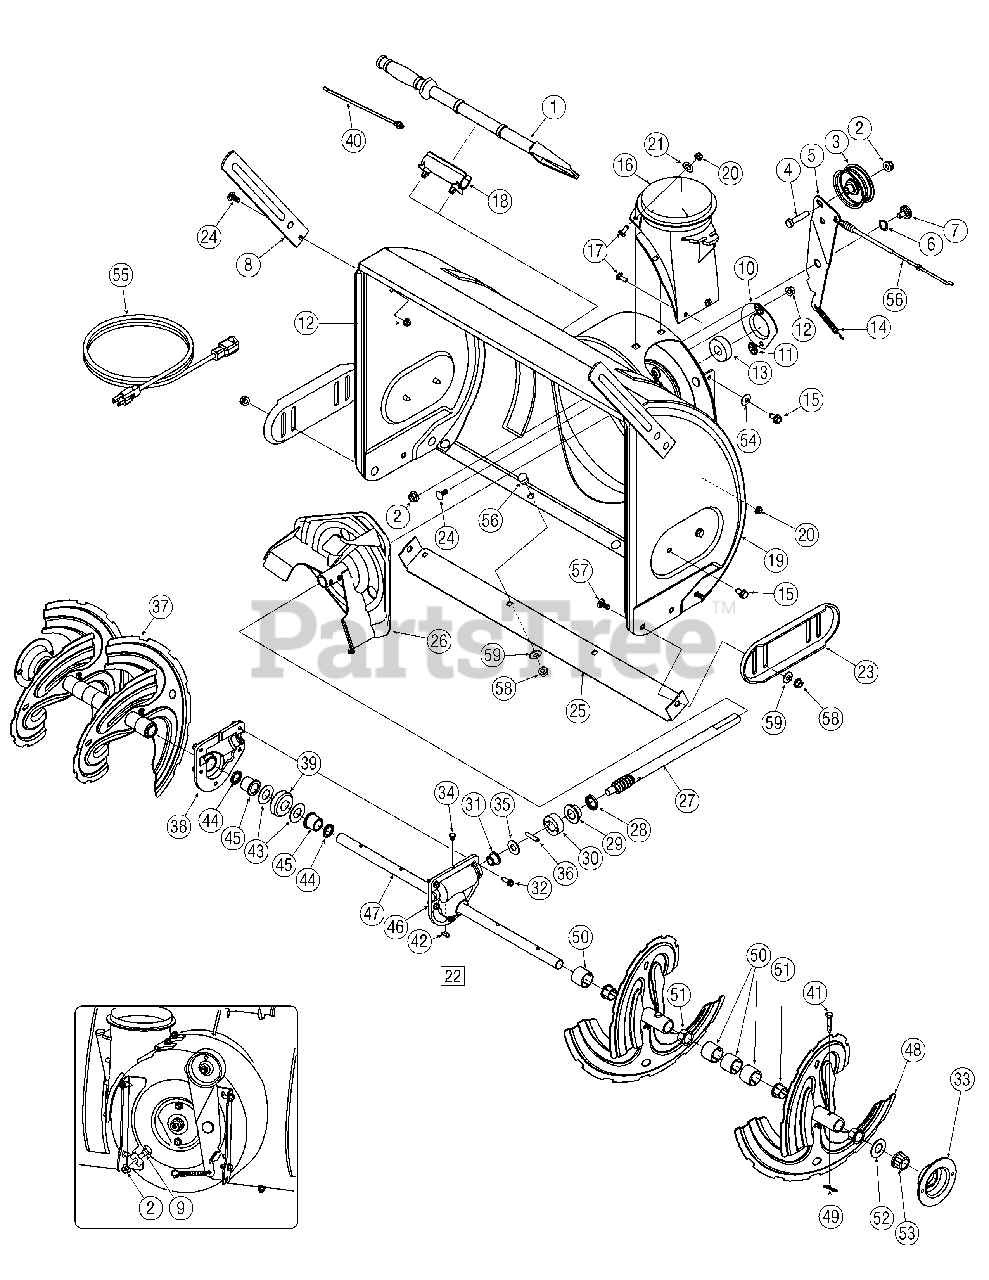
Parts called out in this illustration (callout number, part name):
1	Clean-Out Tool
2	Flange Lock Nut
3	Flat Idler Pulley
4	Hex Bolt, 3/8-16 x 1.75
6	Wave Washer
7	Shoulder Screw
9	Shoulder Screw
10	Bearing Housing
12	Flange Lock Nut, 5/16-18
13	Ball Bearing
14	Extension Spring
15	AB Screw, 5/16-18 x 0.625
16	Chute Adapter
17	Carriage Screw, 1/4-20 x 0.75
18	Clean-out Tool Mtg. Bracket
20	Flange Lock Nut, 1/4-20
21	Flat Washer
22	Gearbox Assembly Complete
23	Slide Shoe
24	Carriage Bolt
25	Shave Plate
27	Worm Shaft
29	Flange Bearing
30	Thrust Collar
31	Flange Bearing
32	TT Screw, 1/4-20 x 0.75
35	Flat Washer
38	Reducer Hsg.-RH (Incl Ref. 44-45)
39	Worm Gear, 20T
40	Cable Tie
42	Key
43	Flat Washer
45	Flange Bearing
46	Reducer Hsg.-LH (Incl Ref. 44-45)
47	Auger Axle
49	Bow Tie Cotter Pin
51	Flange Bushing
52	Flat Washer
53	Hex Flange Bearing
54	Bell Washer
55	Extension Cord
56	Auger Clutch Cable
57	Carriage Bolt, 5/16-18 x .750
58	Hex Nut, 5/16-18
59	Bell Washer, .340 x .872 X .60
